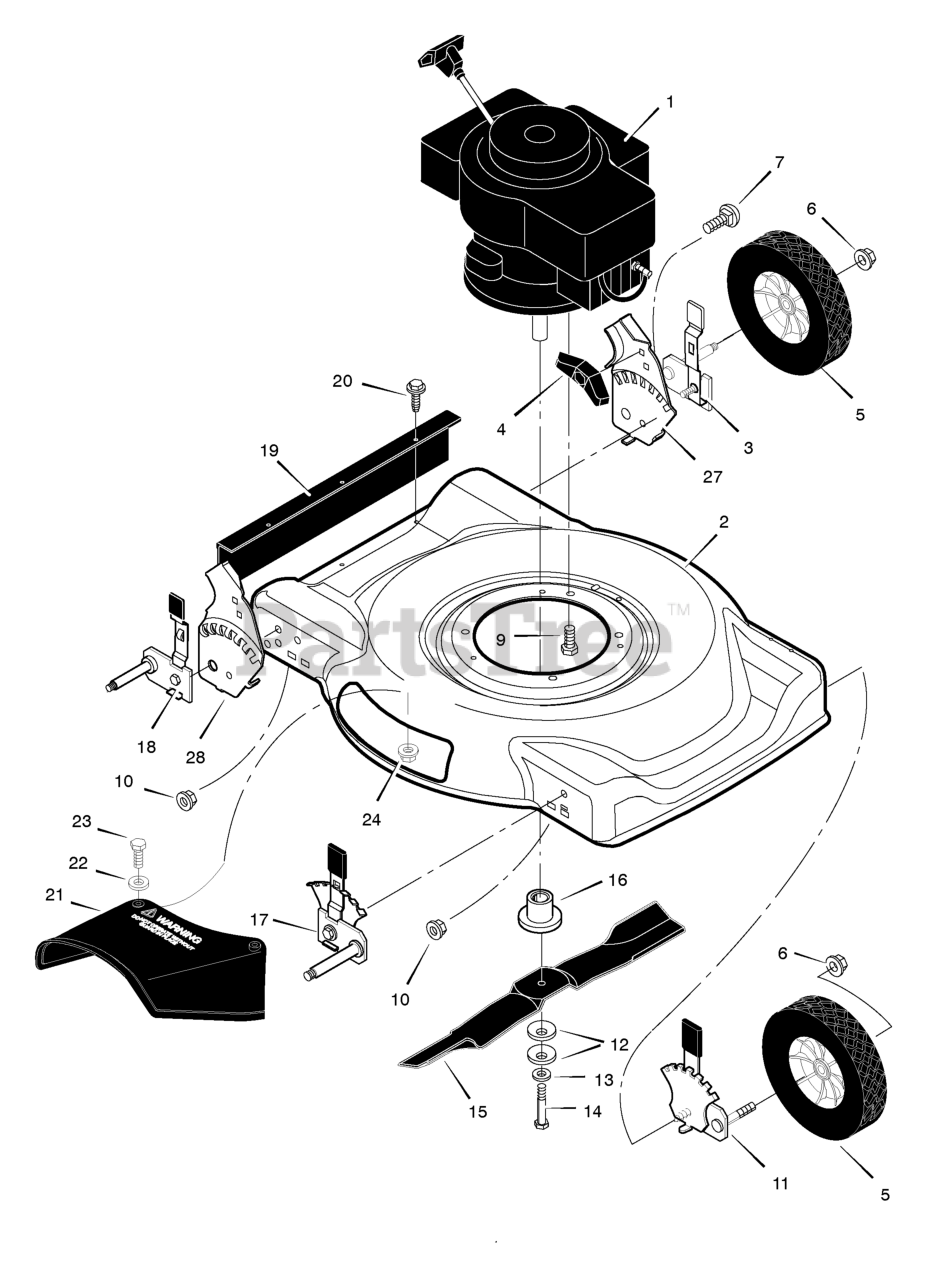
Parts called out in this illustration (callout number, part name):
1	Engine *
2	Housing
3	Height Adjuster, Left Rear
5	Wheel and Tire (White)
6	Locknut, Flange
7	Bolt, Carriage
9	Bolt, Engine
10	Nut
11	Height Adjuster, Left Front
12	Washer, Belleville
14	Bolt, Hex
15	Blade, Side Discharge
16	Adapter, Blade
17	Height Adjuster, Right Front
18	Height Adjuster, Right Rear
19	Guard, Rear
20	Screw
21	Deflector, Chute
23	Bolt, Hex
24	Nut, NYLOCK
27	Bracket, Left Handle
28	Bracket, Right Handle
